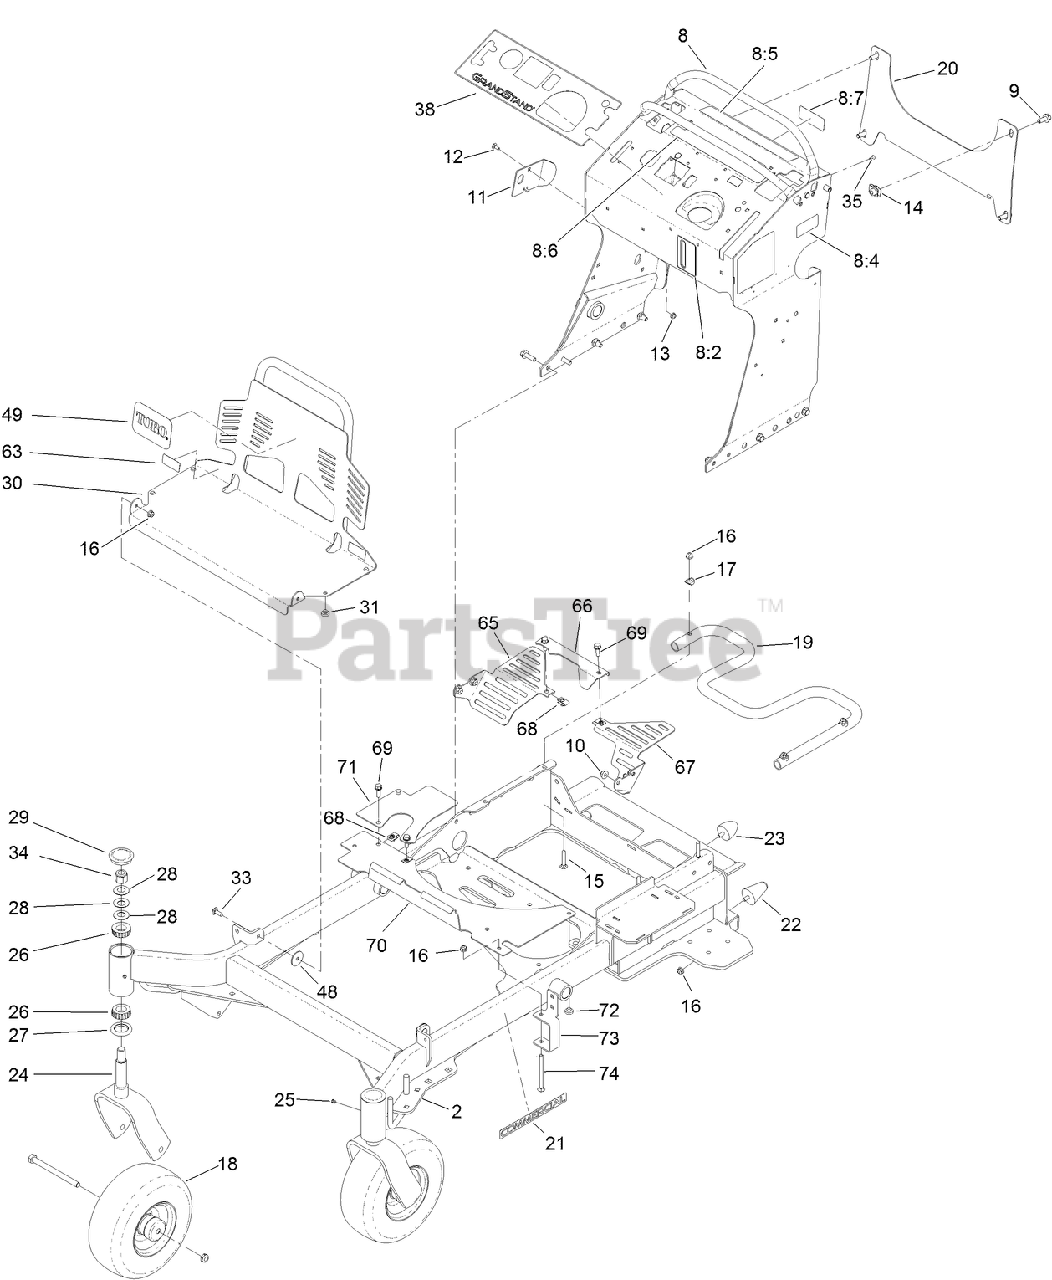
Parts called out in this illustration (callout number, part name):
8	TOWER DECAL ASM
8:2	DECAL-LEVEL, OIL
8:4	DECAL-FILL, FUEL
8:5	DECAL-CAUTION
8:6	DECAL-CONTROLS
8:7	DECAL-FUSE
9	SCREW-HHF
10	NUT-HF, NI
11	PLATE-STRIKER
12	SCREW-CARR
13	NUT-HF
14	NUT-TINNERMAN
15	BOLT-CAR
16	NUT-HF, NI
17	WASHER
18	WHEEL/TIRE AND BEARING ASM
19	TUBE-MOUNT, FUEL TANK
20	BRACKET-CROSS
21	DECAL-COMMERCIAL
22	BUMPER-RUBBER
23	BUMPER-RUBBER
24	FORK-CASTER
26	BEARING-ROLLER, TAPERED
27	SEAL-GREASE
28	WASHER-BELLVILLE
29	CAP-GREASE
30	GUARD-ENGINE
31	BUMPER
33	BOLT-CARR
34	NUT-LOCK, NI
35	RIVET-POP
38	DECAL-PANEL, CONTROL
48	WASHER-NYLON
63	DECAL-WARNING, NO RIDERS
65	GUARD-FAN, RH (CE)
66	GUARD-FAN, CENTER (CE)
67	GUARD-FAN, LH (CE)
68	NUT-U
69	SCREW-HHF
70	GUARD-EXTENSION
71	GUARD-BELT, CE
72	BUMPER
73	BRACKET-MOUNTING, GUARD
74	SCREW-CARR
